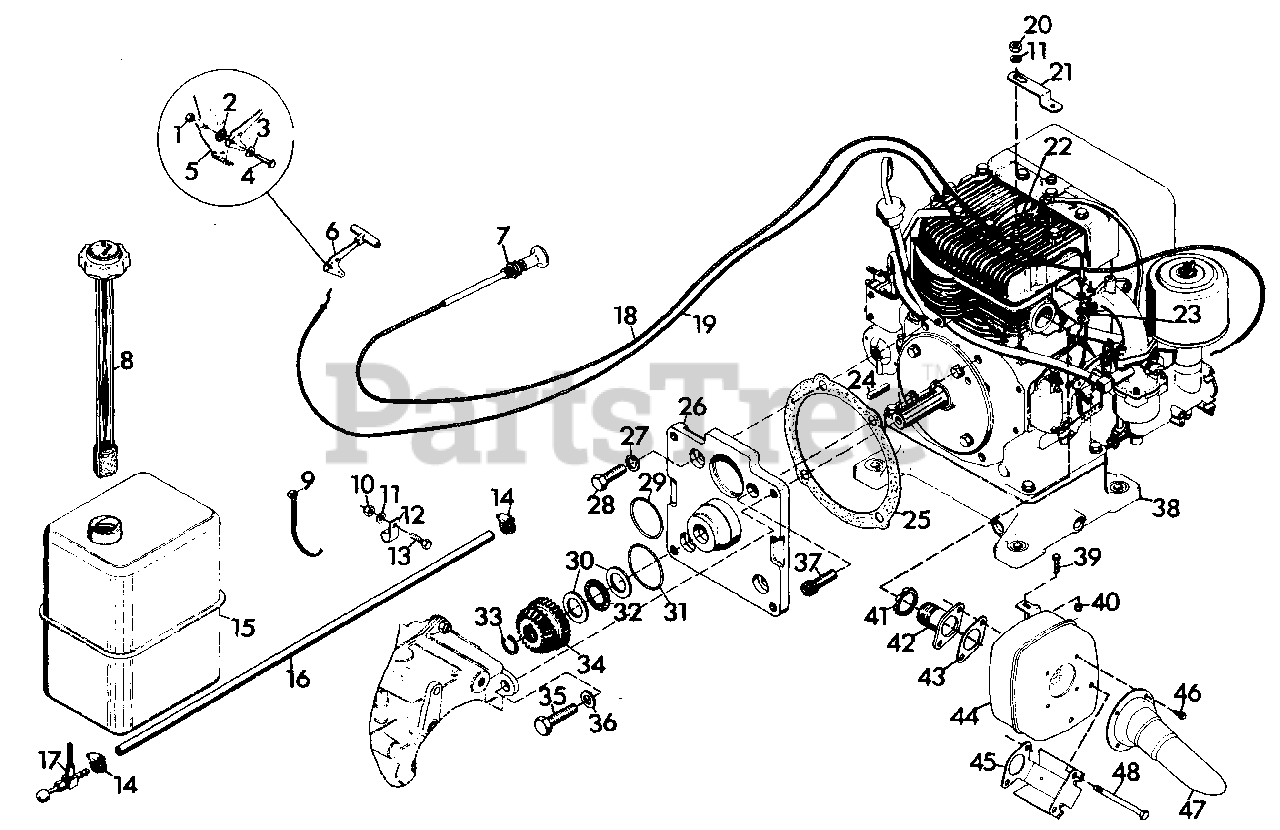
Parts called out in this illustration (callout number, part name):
1	NUT, LOCK 1/4-28
2	WASHER, FRICTION
3	WASHER, SPRING
4	BOLT, HEX 1/4-28X.75
5	BRACKET, MOUNTING
6	ASSEMBLY, KNOB AND LEVER
7	NUT, JAM 3/8-24 HEX
8	GAUGE, GAS
9	TIE, CABLE
10	NUT, LOCK 5/16-18
11	WASHER, FLAT .344X.688X.065
12	CLAMP, NYLON
13	BOLT, HEX 5/16-18X1.00
14	CLAMP, HOSE
15	TANK, FUEL
16	LINE, FUEL
17	VALVE, FUEL 90 DEG. REVERSE FLOW
18	CONTROL, CHOKE
19	ASSEMBLY, THROTTLE CONDUIT
20	NUT, HEX 5/16-18
21	BRACKET, MUFFLER
22	STUD, MUFFLER
23	NUT, PLASTIC CONDUIT
24	KEY, SQUARE .250X1.250
25	GASKET, ADAPTOR
26	ADAPTOR, ENGINE
27	WASHER, LOCK 7/16 SP HEAVY
28	BOLT, HEX 7/16-14X1.125
29	O-RING, 2.500X2.750X.125
30	RACE, BEARING THRUST 1.125X1.750X.123/.126
31	O-RING, 3.000X3.188X.094
32	BEARING, THRUST 1.127X1.740X.078
33	RING, RETAINING 1.125 SHAFT
34	GEAR, SPUR AND BEVEL, INPUT
35	BOLT, HEX 1/2-13X1.25
36	WASHER, LOCK 1/2 REG.
37	SCREW, CAP 7/16-14X1.0 SOCKET HEAD
38	ENGINE, 16 HP B&S
39	BOLT, HEX 1/4-20X.75
40	NUT, LOCK 1/4-20
41	NUT, CONDUIT 1" PIPE
42	WELDMENT, MUFFLER ADAPTOR
43	GASKET
44	MUFFLER
45	SHIELD, MUFFLER
46	SCREW, TAPPING
47	DEFLECTOR, EXHAUST
48	BOLT, HEX SHOULDER
NS	NUT, LOCK 10-32
NS	SCREW, MACHINE 10-32X.50 PHD
